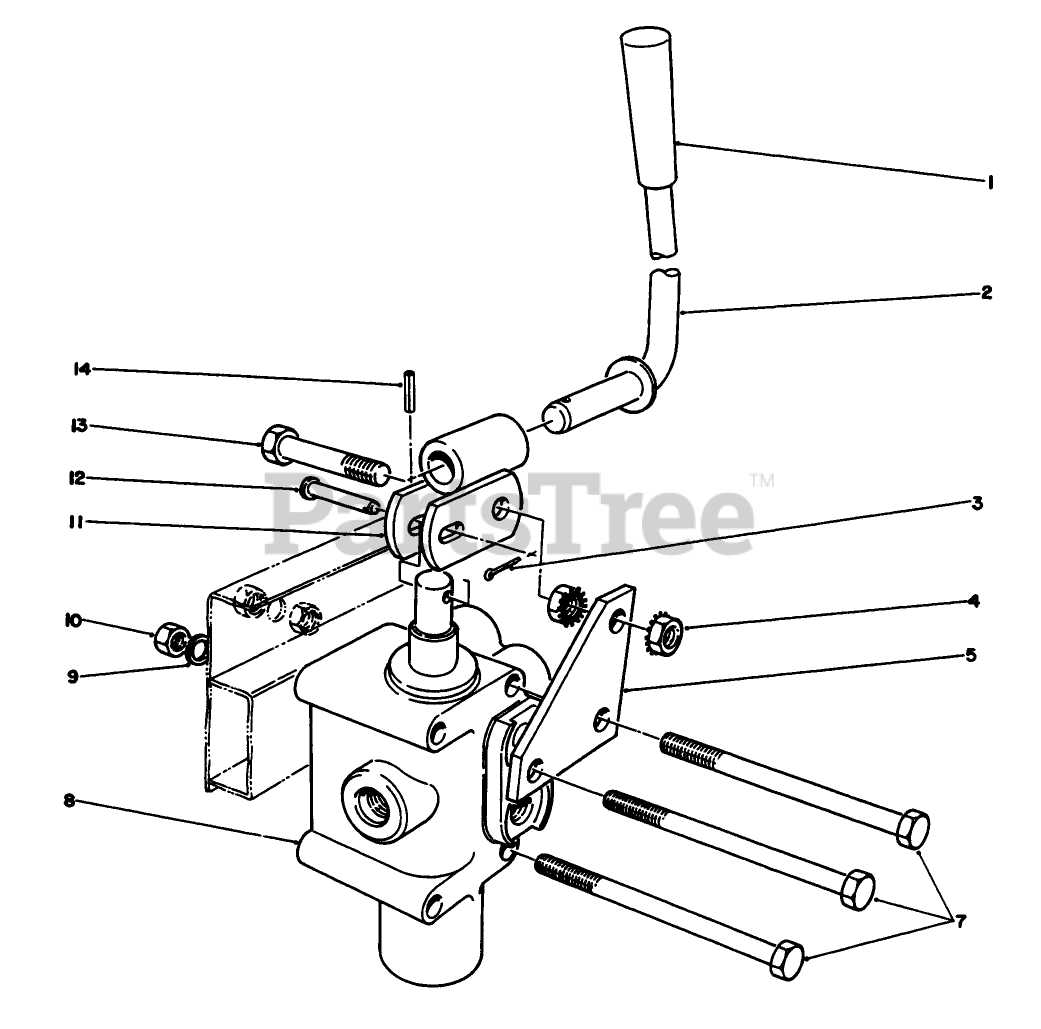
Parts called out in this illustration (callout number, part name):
1	KNOB-CONTROL
2	Lever-Valve
3	PIN-COTTER
4	NUT-KEPS
5	Wheel Bolt
7	SCREW-HH
8	VALVE ASM
9	WASHER-LOCK
10	NUT-HF
11	Valve Lever Link
12	PIN-CLEVIS
13	SCREW-HH
14	PIN-ROLL
